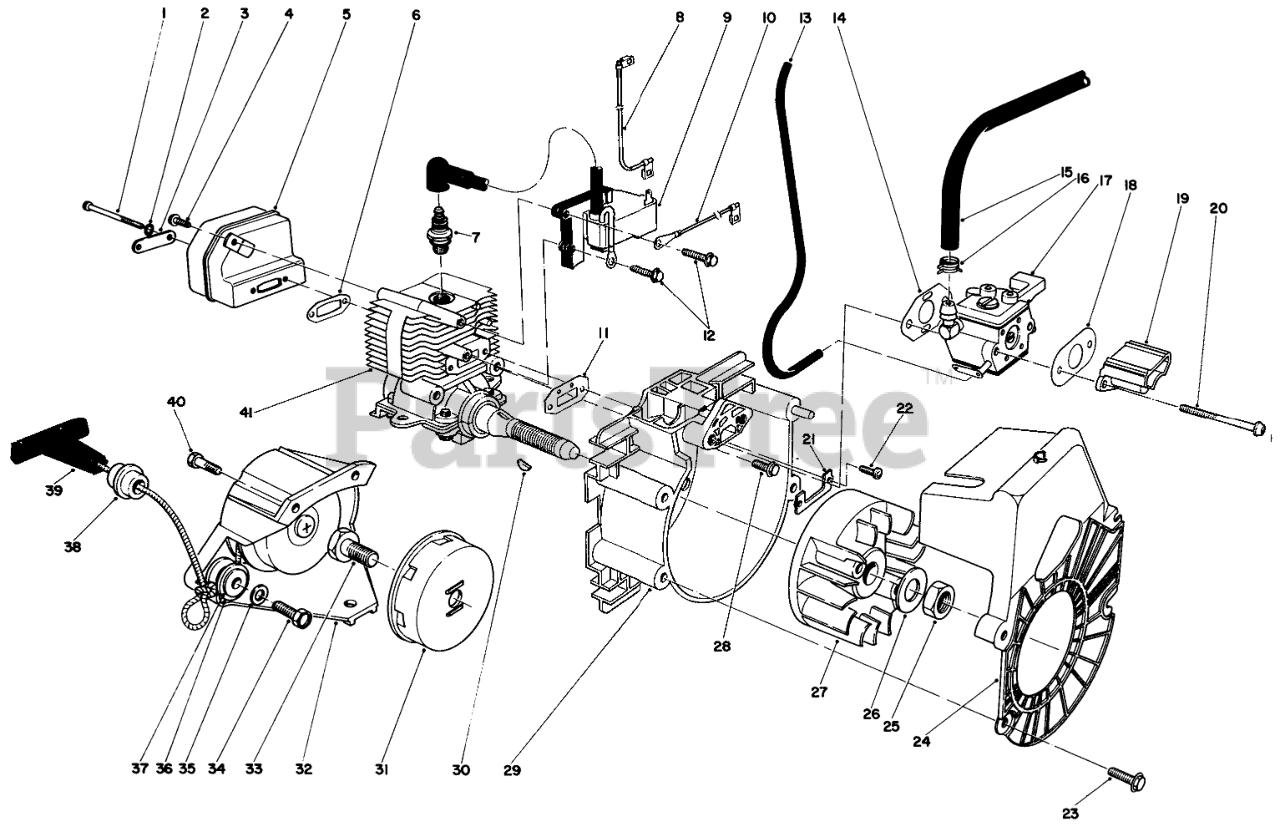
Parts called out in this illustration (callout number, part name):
1	MUFFLER SCREW
2	WASHER-LOCK
3	Stress Plate, Muffler
4	Screw, Muffler Tab
5	Muffler Assembly
6	EXHAUST GASKET
7	SPARK PLUG
8	Wire Assembly-Coil
9	BIM Module
10	Wire Assembly-Ground
11	Gasket, Intake
12	Screw CDI
13	HOSE-PRIMER
14	Gasket, Carburetor
15	Hose Fuel
16	CLAMP-HOSE
17	Carburetor
18	CHOKE GASKET
19	Spit Back Cup
20	Screw-Carburetor
21	Plate-Stress
22	Screw lntake
23	Screw-Shroud
24	Cooling Shroud
25	NUT-JAM
26	Washer, Flywheel
27	Flywheel
28	Screw
29	Backing Plate Assembly
30	FLYWHEEL KEY
31	Cup, Starter
32	Starter Assembly (Incl. Ref. #34-39)
33	Spark Plug
34	Screw, Idler Pulley
35	Washer, Brake
36	Idler Pulley (Incl. Ref. #37)
38	Guide Rope
39	Handle
40	Screw
41	SHORT BLOCK ASM
